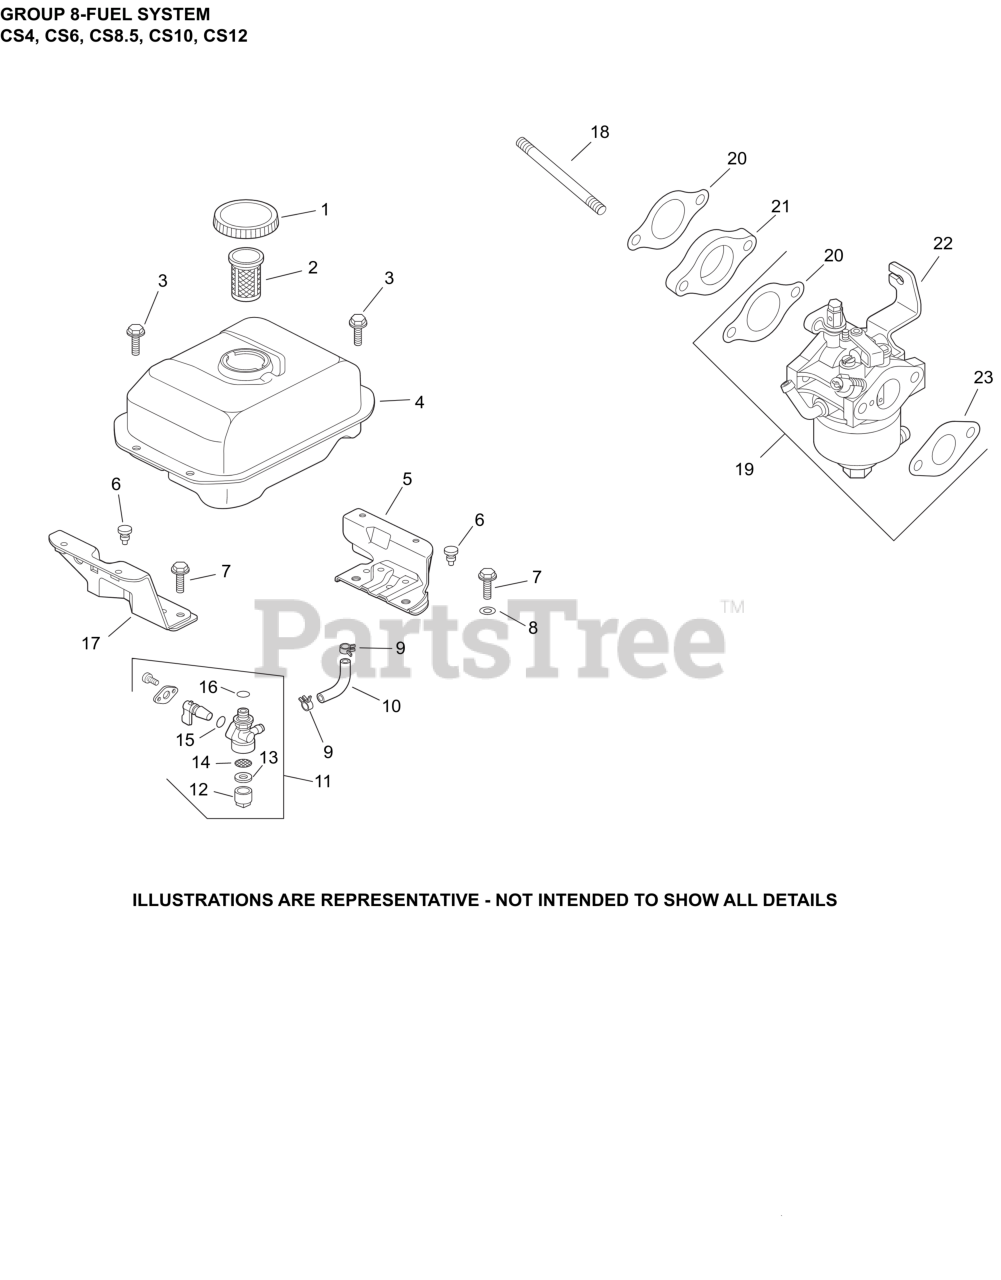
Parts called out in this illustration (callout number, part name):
1	CAP, FUEL TANK
4	TANK, FUEL
5	BRACKET, FUEL TANK
10	LINE, FUEL-DISCONTINUED
11	VALVE, FUEL COCK ASSEMBLY
12	CUP, FILTER
14	FILTER SCREEN-DISCONTINUED
17	BRACKET-FUEL TANK
18	STUD, CARBURETOR
19	KIT, CARBURETOR W/GASKET (CS6)
20	GASKET, INTAKE
21	MANIFOLD, INTAKE
NI	SEAL, GAS CAP
NI	GASKET, BOWL
NI	GASKET, BOWL SCREW
NI	SCREW, FLOAT BOWL
NI	SCREW, PAN HEAD
NI	O-RING, FUEL VALVE
NI	CAP, CARBURETOR ADJUSTING
